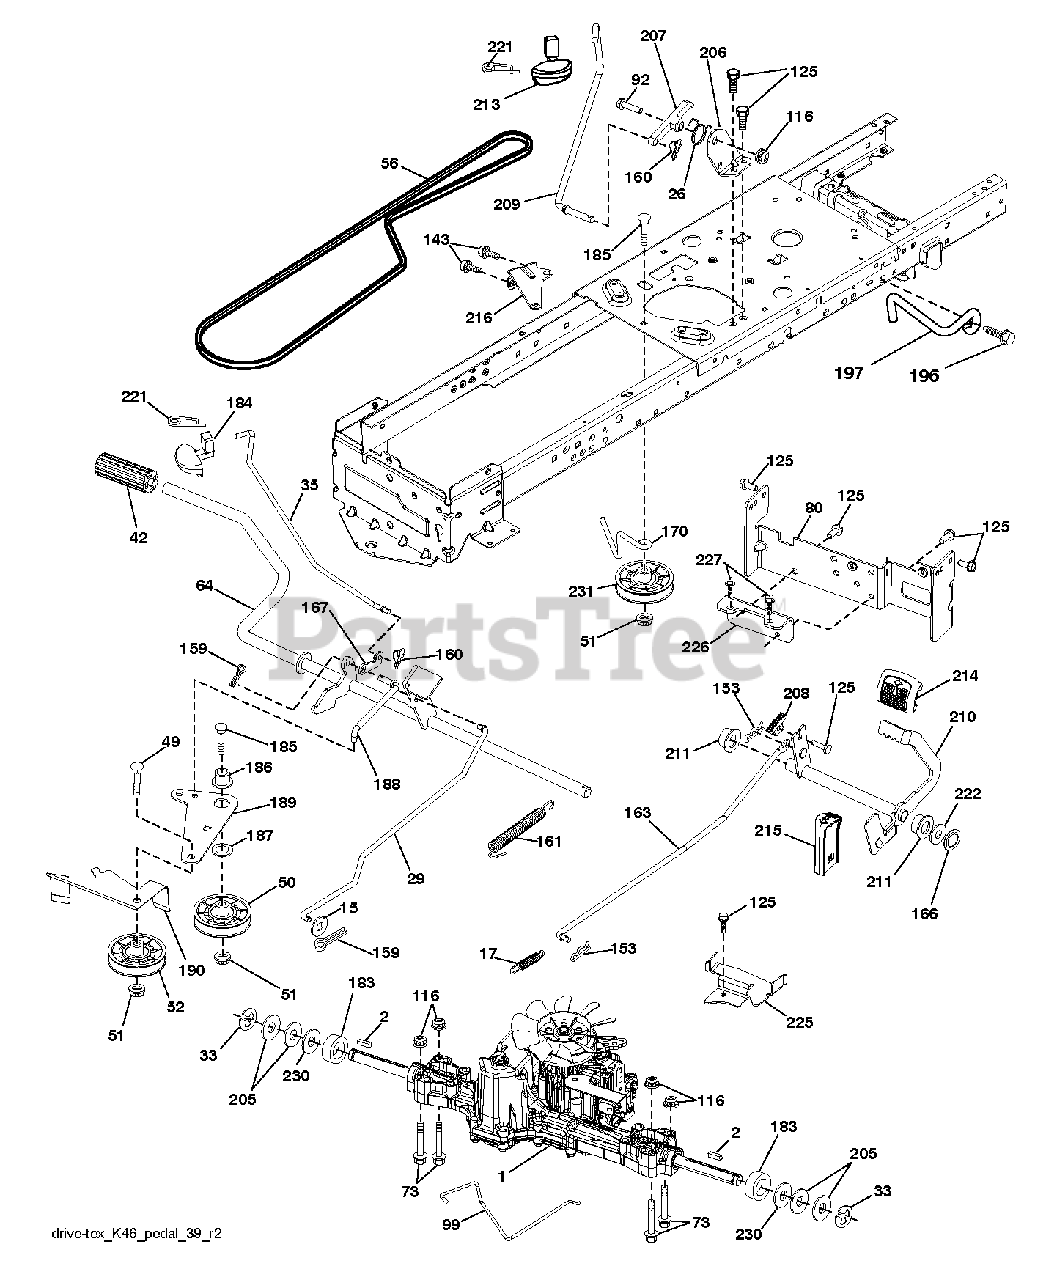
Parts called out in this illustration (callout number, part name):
2	SQUARE KEY
15	WASHER
17	SPRING.BRAKE.K46.GREEN
26	SPRING.RETURN.CRUISE
29	ROD.BRAKE.K46
35	ROD.BRAKE.PARTK.HUSQ.TEX
42	PEDAL COVER T
50	IDLER.FLAT.910.OFFSET
51	NUT LOCK FLG 3/8-16 UNC
52	IDLER.V-GROOVE.910.OFFSET
56	V-BELT.MOWER.92.40.42/K46
64	SHAFT.ASM.PEDAL.BRK.CNTR
80	STRAP.TORQUE.K46.K57R.TT
92	BOLT
99	ROD.SPRING.BYPASS.K46.LT.Z
116	NUT LOCK HEX FLANGE 5/16-18
125	SCREW
143	SCREW LT
153	RETAINER M
159	COTTER PIN
160	RETAINER CLIP
161	SPRING, RETURN LT
163	ROD.CONTROL.K57R.K46
166	NUT.PUSH.625
167	LATCH.BRAKE.SPRING
170	KEEPER.CENTER SPAN.1.688
183	SPACER AXLE
184	RB HANDLE.PARKG.BRK.HUS/PRED
186	SPACER.RETAINER
187	WASHER 12/32X2X10GA
188	RP LINK.CLUTCH.GROUND.DRIVE
189	BELLCRANK.GROUND.DRIVE.TEX.
190	KEEPER.BELLCRANK.DRIVE
196	SCREW 3/8-16X1
197	LINK.CLUTCH.ANIT-ROTAT
206	BRKT.MOUNT.LATCH.CRUIS
207	LATCH.CONTROL.CRUISE
208	GEAR.SECTOR.CONTROL.CR
209	ROD.CONTROL.CRUISE.GT.
210	ROCKER.ASM.PEDAL.CONTR
211	BEARING.NYLON
213	KNOB.CONTROL.CRUSIE.HU
214	PEDAL.FORWARD.PAD.TEX
215	PEDAL.REVERSE.TEX.GT.4
216	BRACKET.PULLEY.IDLER.W/TEX
221	RETAINER.SPRING.CLIP.H
222	WASHER 21/32 X 1-1/4 X 10 GA.
225	KEEPER.BELT.TRANSAXLE.K46
226	BRACKET.MOUNT.TORQUE.K46.TLT
227	SCREW
230	WASHER.HARDENED
231	IDLER.V-GROOVE.1.688.OFFSET
